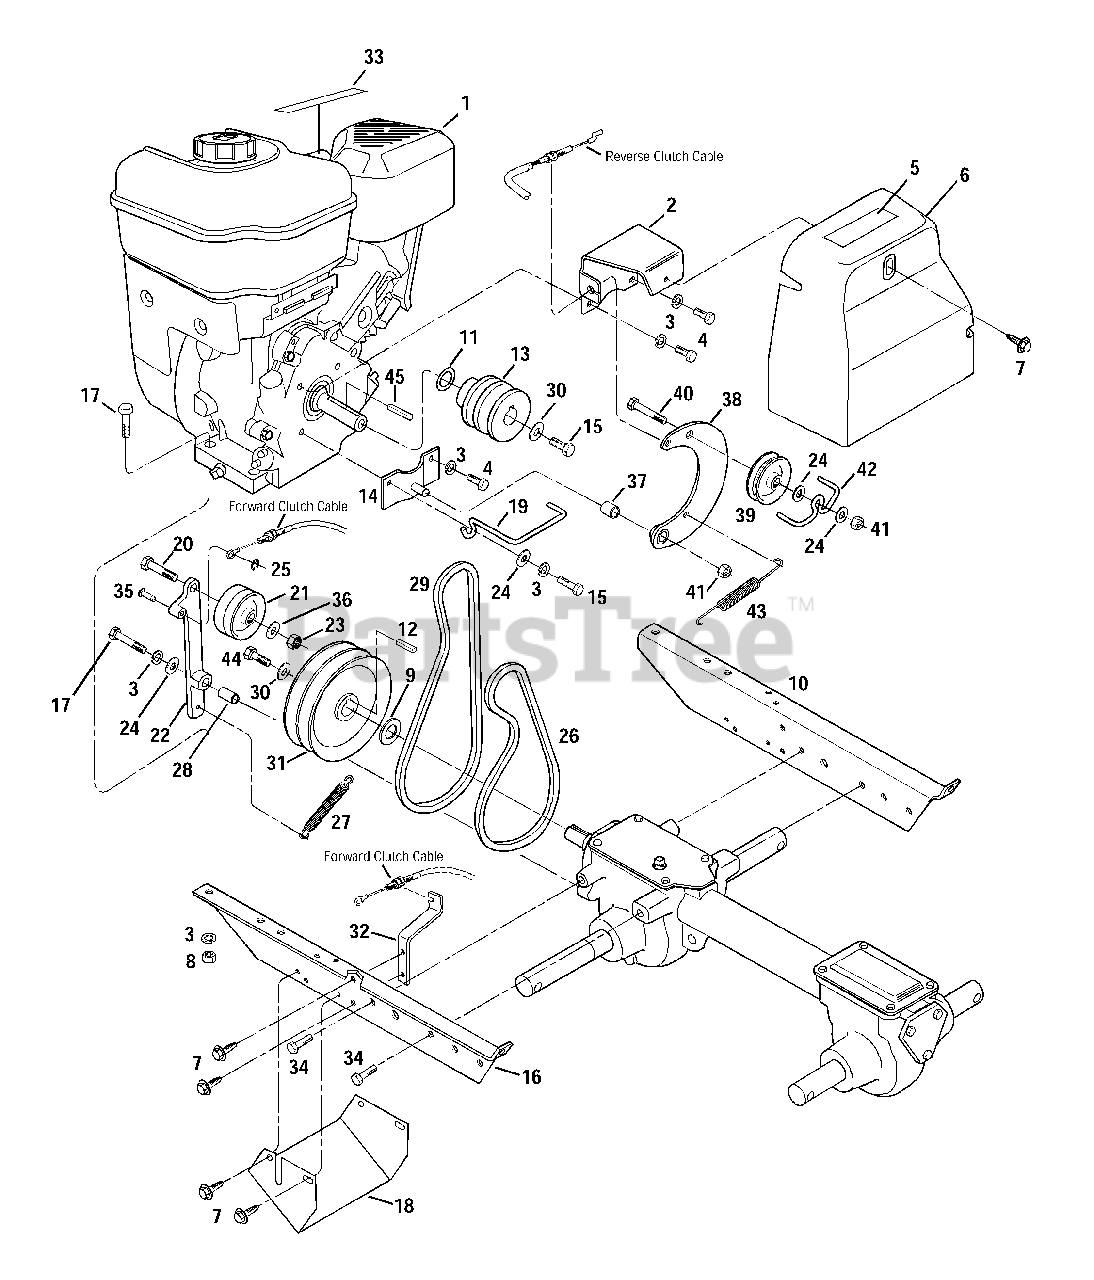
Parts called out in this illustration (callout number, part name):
1	Engine-5HP & 6.5HP, Recoil Start
2	Bracket, Belt Cover
3	Lockwasher, 5/16
4	Screw, Hex Hd., 5/16-24 x 1/2
5	Decal-Warning, Hot Surfaces
6	Belt Cover
7	Flange Screw, Self-Tapping, 1/4-20 x 1/2.
8	Hex Nut, 5/16-18
9	Support Washer
10	Engine Bracket, Right
11	Shim
12	Key, 3/16 x 1
13	Pulley, Engine Drive
14	Bracket, Reverse Idler
15	Hex Screw, 5/16-24 x 1
16	Engine Bracket, Left
17	Hex Screw, 5/16-18 x 1-1/2
18	Guard, Belts/Pulleys
19	Belt Guide, Forward
20	Hex Screw, 3/8-16 x 1-1/2
21	Forward Idler Pulley
22	Forward Idler Lever
23	Locknut-3/8-16
24	Washer, Flat
25	Klip Ring
26	Forward Drive Belt
27	Spring, Forward Return
28	Bushing, Forward Idler Lever
29	Reverse Drive Belt
30	Washer, Belleville
31	Pulley, Transmission
32	Bracket, Cable Mounting
33	Decal-Stabilization
34	Hex Screw, 5/16-18 x 5/8
35	Clevis Pin
36	Flat Washer, 3/8
37	Bushing
38	Reverse Idler Arm
39	Pulley, Reverse Idler
40	Hex Screw, 5-16-18 x 2
41	Locknut, 5-16-18
42	Belt Guide
43	Spring, Reverse Return
44	Hex Screw, 5/16-18 x 1-1/8
45	Key, 3/16 x 1-1/2
